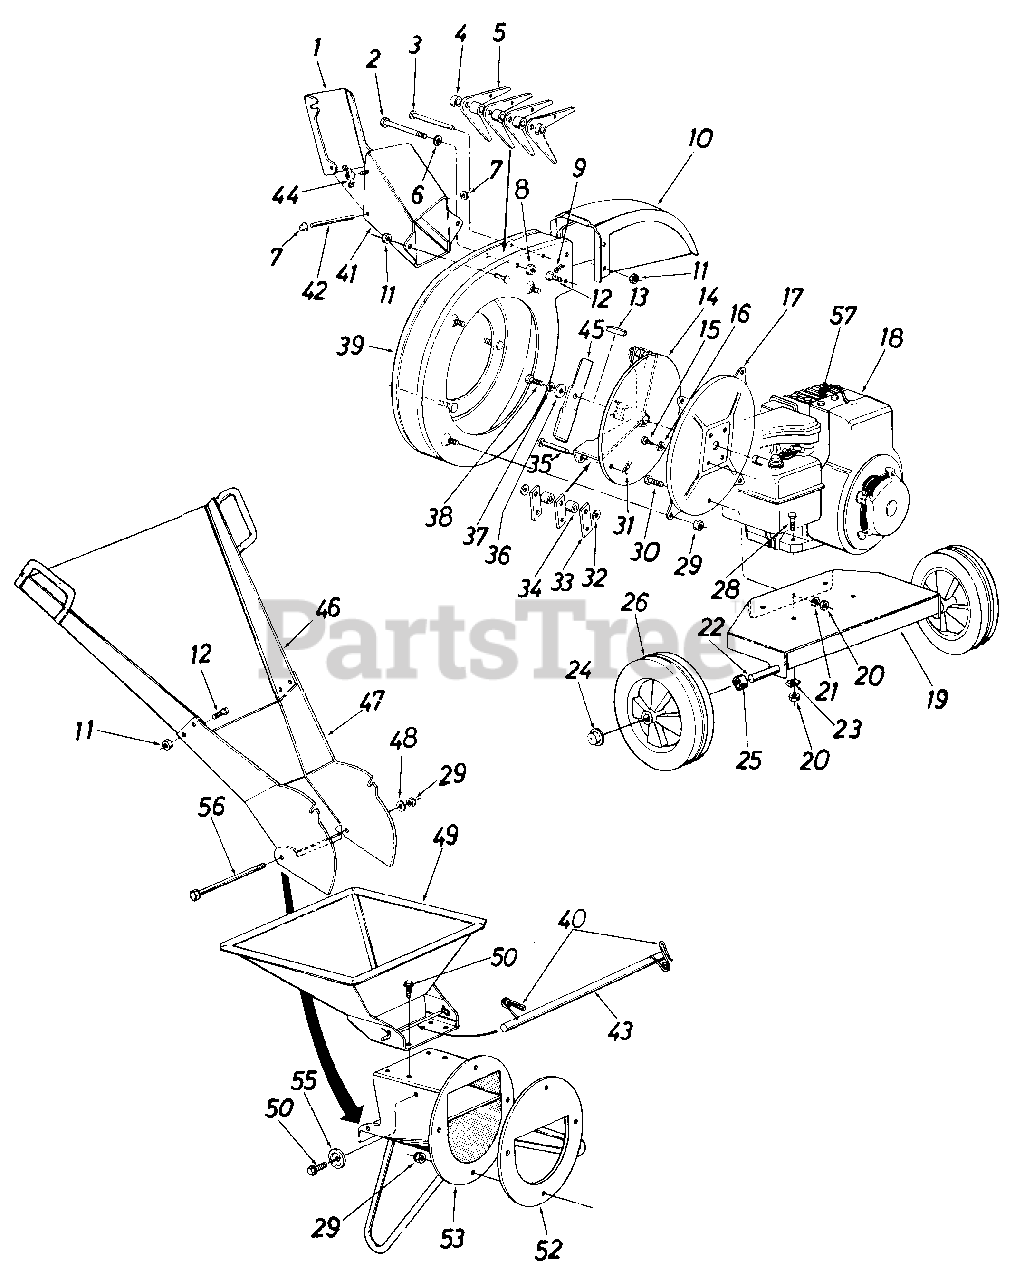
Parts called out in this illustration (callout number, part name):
1	Door Chip It
2	Hex Bolt 1/2-20 x 4.50" Lg.*
3	Clevis Pin
4	Flail Spacer 7/32" Lg.
5	Cuting Finger
6	L-Wash. 1/2" I.D.*
7	Palnut 3/16" Dia.
8	Hex Jam Nut 1/2-20 Thd.*
9	Coter Pin 3/32" Dia. x 3/4" Lg.
10	Chute Deflector
11	L.-Nul 1/4-20 Thd.
12	Hex Bolt 1/4-20 x .50" Lg.*
13	Sq. Key 1/4" x 2.00" Lg.
14	Impeller Assembly
15	Hex Bolt 5/16-24 x 3/4" Lg.
16	L.Wash. 5/16" I.D.*
17	Hopper to Engine Mtg. Plate
18	Engine
19	Engine Mounting Plate
20	Hex Nut 5/16-24 Thd.*
21	L.Wash. 5/16" I.D.*
22	Shaft
23	Special L.Wash. 5/16" I.D.
24	Push Cap
25	Spacer
26	Wheel Ass'y.Comp.
28	Hex Bolt 5/16-24 x 1.50" Lg.
29	Elastic Lock Nut 5/16-18 Thd.
30	Hex Bolt 5/16-24 x .62" Lg.*
31	Coter Pin 1/8" Dia. x 1.00" Lg.*
32	Fl.Wash. .531" I.D. x 937 O.D. x .09
33	Flail
34	Flail Spacer 23/32" Lg.
35	Clevis Pin .50" Dia. x 3.0" Lg.
36	Fl.Wash. .406" I.D. x 1.25" O.D. Hdn.
37	L.Wash. 3/8" I.D. H.D.
38	Hex Bolt 3/8-24 x 2.0" Lg. H.T.
41	Chip-lt Guide Ass'y.
42	Hinge Pin
43	Release Bar
44	Wing Nut Elastic 1/4-20 Thd.
47	Lower Leaf Ramp Section
48	Fl.Wash. 5/16" I.D.
49	Hopper Assembly
50	Hex Wash. Hd. Self-Tap Scr. 5/16-18 x .75" Lg.
52	Back-Up Plate
53	Inlet Guide Assembly
55	Stop Washer
56	Hex Bolt 5/16-18 x 8.38" Lg.
57	Spark Plug Boot
